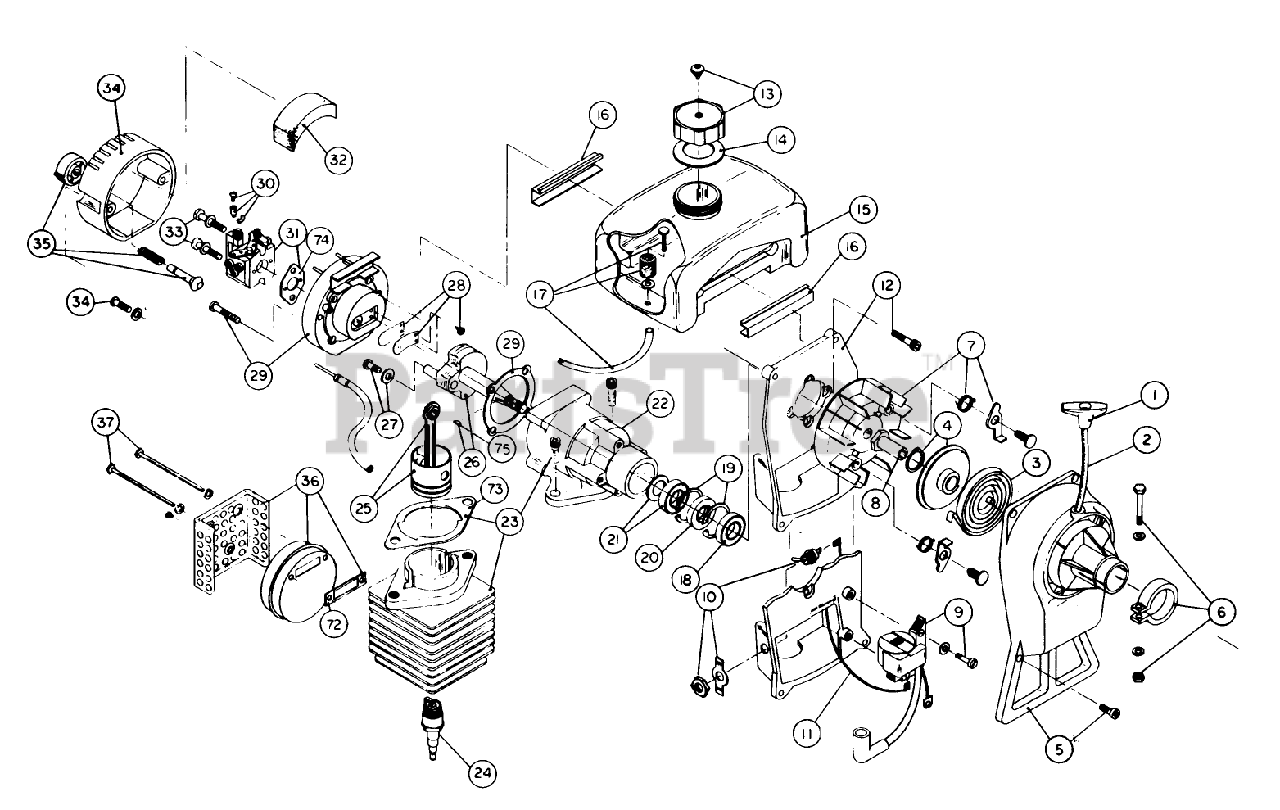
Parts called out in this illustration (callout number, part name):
8	SQUARE DRIVE NUT
10	SWITCH ASM
17	FUEL LINE ASM
18	OUTER BEARING
21	INNER BEARING ASM
24	SPARK PLUG
26	Power shaft assembly
30	THROTTLE ADJ ASM
37	MUFFLER MOUNTING BOLTS
74	CARB.GASKET
75	FLYWHEEL KEY (10-PK)
